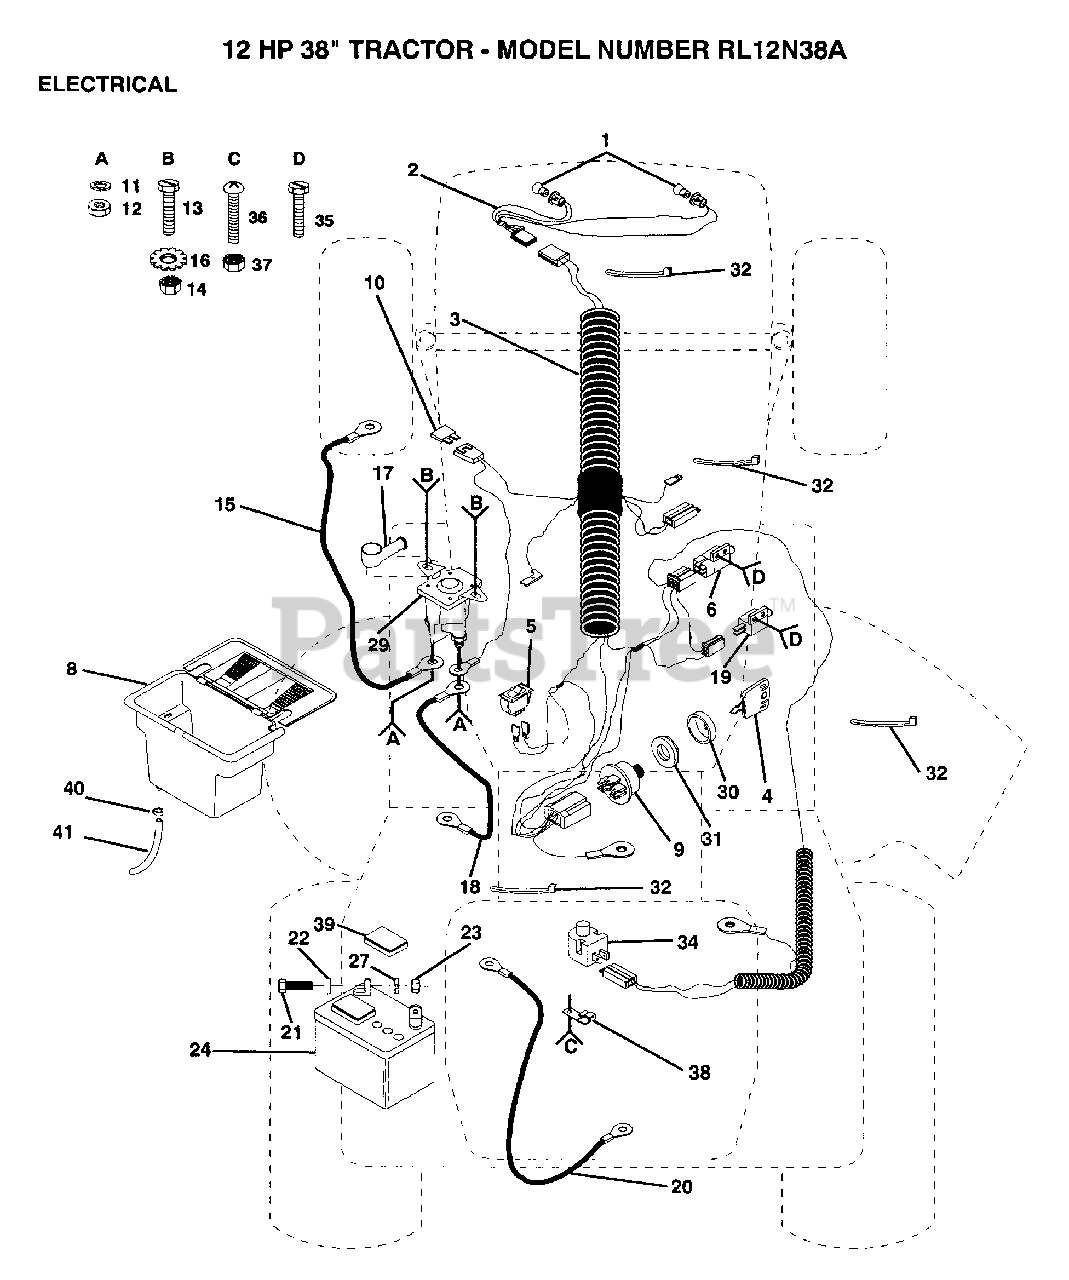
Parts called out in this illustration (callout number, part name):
3	IGN HARNESS
4	KEY
5	SWITCH LT
6	SWITCH INTERLOCKT
10	FUSE HYT
12	NUT
13	BOLT
14	NUT
15	"CABLE T, BATTERY"
19	SWITCH-INTER. GT
20	CABLE T
21	BOLT LT
22	WASHER
27	LOCKWASHER
31	NUT IGNITION
32	WIRE TIE
34	SWITCH SEAT
35	SCREW
37	"NUT,KEPS"
39	"CAP,BATTERY "
40	HOSE CLAMP T
